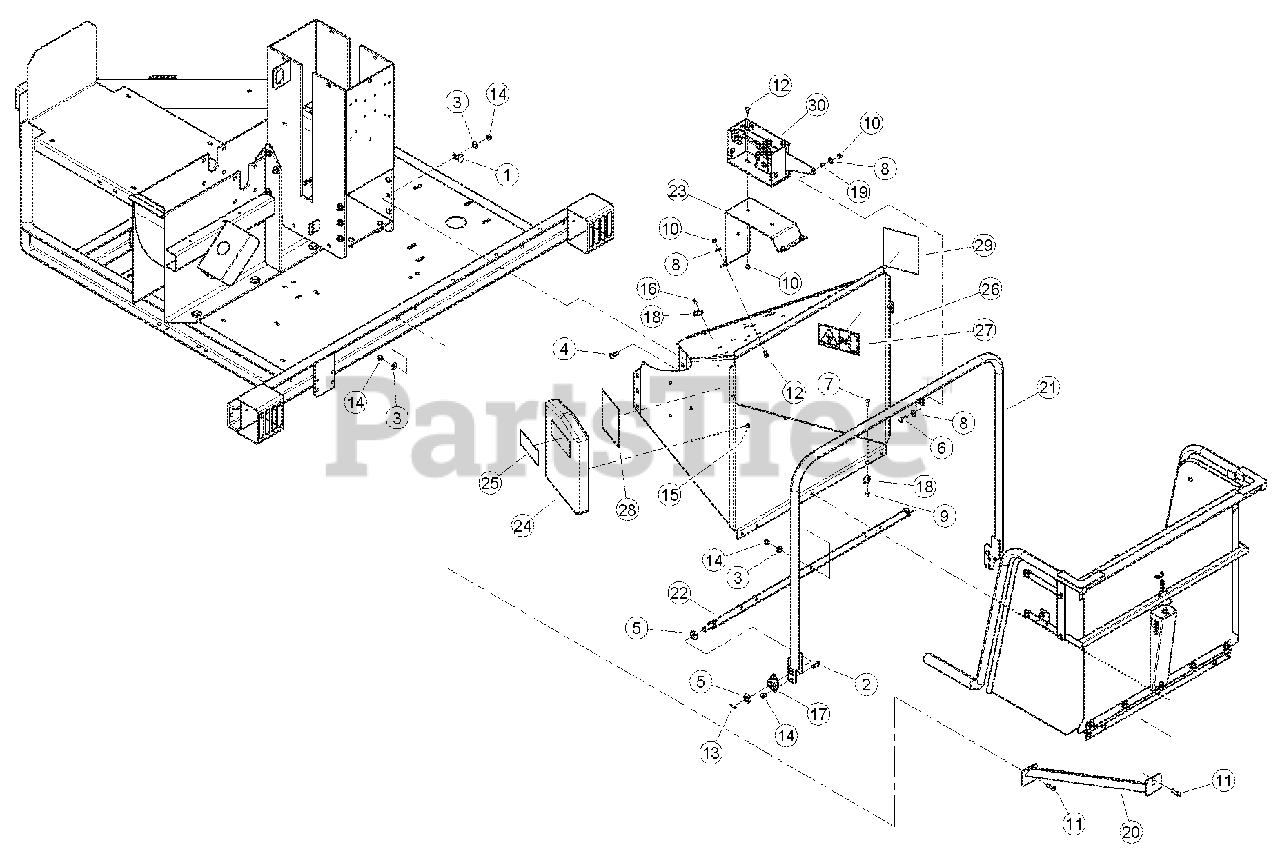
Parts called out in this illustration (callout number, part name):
1	CLAMP, 9/16" COATED
2	BOLT, 3/8 X 1 HEX HD GR5 ZP
3	WASHER, 3/8 FLAT ZP
4	BOLT, 3/8 X 1-1/2 CRG GR5 NC ZP
5	WASHER, 5/8 SAE FLAT ZP
6	BOLT, 5/16 X 1 HHCS GR5 NC ZP
7	BOLT, 1/4 X 1 CRG GR5 NC ZP
8	WASHER, 5/16 FLAT ZP
9	NUT, 1/4 NE NYLOCK ZP
10	NUT, 5/16 NE NYLOCK ZP
11	BOLT, 3/8 X 1-1/4 HEX HD GR5 ZP
12	BOLT, 5/16 X 3/4 CRG GR5 NC ZP
13	PIN, 1/8 X 1.00 ZP COTTER
14	NUT, 3/8 NE NYLOCK ZP
15	RIVET, AL BLIND 1/4 X 1/2 DOME HEAD
16	RIVET, AL BLIND 1/4 X 3/4 DOME HEAD
17	BEARING, SIDE FLANGE MOUNT, 5/8
18	CLAMP, CABLE MOUNT
19	SPACER, IDLER PIVOT
20	WELDMENT, CHUTE SUPPORT
21	WELDMENT, CONTROL ARM
22	WELDMENT, CONTROL PIVOT
23	MOUNT, SWITCH BOX
24	ASSEMBLY, MANUAL CONTAINER, SERVICE PART
25	DECAL, MUTILINGUAL MANUAL
26	ASSEMBLY, BIG CHIPPER CHUTE, SERVICE PART
27	DECAL, BLADE DANGER ISO
28	DECAL, FEED POSITION
29	DECAL, FEED POSITION
30	ASSEMBLY, SWITCH BOX
